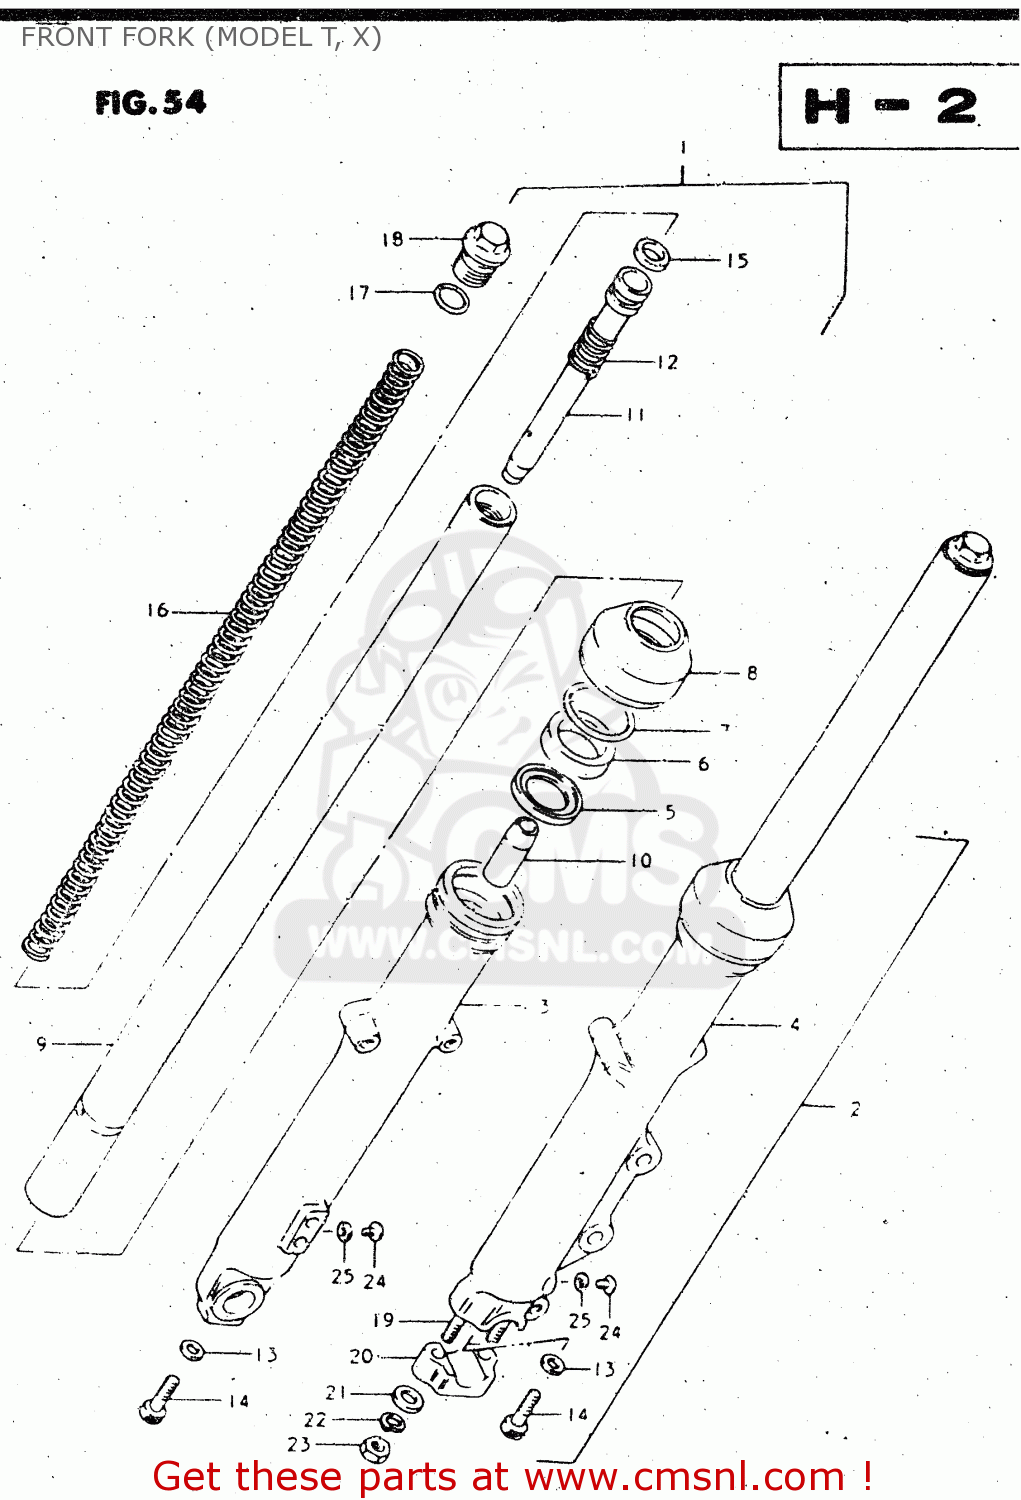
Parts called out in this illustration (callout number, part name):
1	DAMPER ASSEMBLY,RIGHT
2	DAMPER ASSEMBLY,LEFT
3	TUBE,FORK,OUTER,RIGHT
4	TUBE,FORK,LEFT,OUTER
5	SPACER,OIL SEAL
6	OIL SEAL,FRONT FORK
7	CIRCLIP,FORK OIL SEAL
8	BOOT
9	TUBE,FORK,INNER
10	PIECE,OIL LOCK
11	CYLINDER,FRONT FORK
12	SPRING,REBOUND
13	GASKET (NAS)
14	BOLT(8X27)
15	RING,PISTON
16	SPRING
17	O RING
18	BOLT
19	STUD 8X25
20	HOLDER,AXLE
21	WASHER
22	LOCK WASHER
23	NUT (8MM)
24	SCREW 4X6
25	GASKET (NAS)
